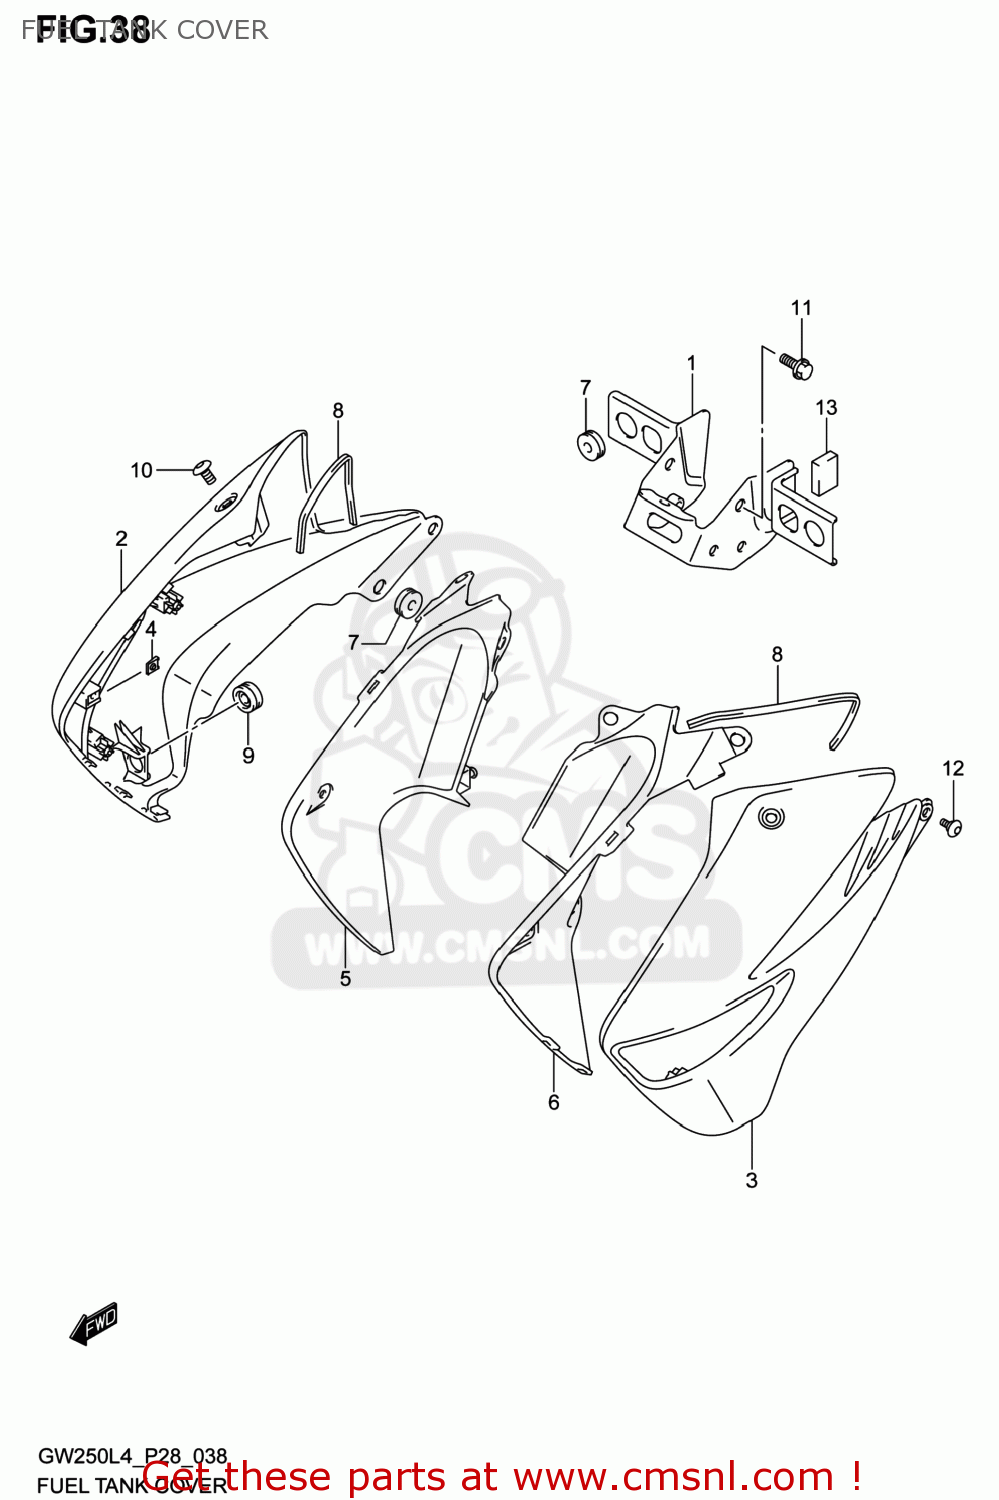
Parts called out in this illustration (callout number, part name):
1	BRACKET,FR SIDE COVER
2	COVER,FUEL TANK,R
3	COVER,FUEL TANK,L
4	NUT,FUEL TANK COVER
5	COVER,FUEL TANK FR,R
6	COVER,FUEL TANK FR,L
7	CUSHION,FUEL TANK COVER
8	CUSHION,FUEL TANK COVER SIDE
9	CUSHION,FUEL TANK COVER
10	SCREW(6X10)
11	BOLT
12	SCREW(6X12)
13	CUSHION,COVER BRACKET
